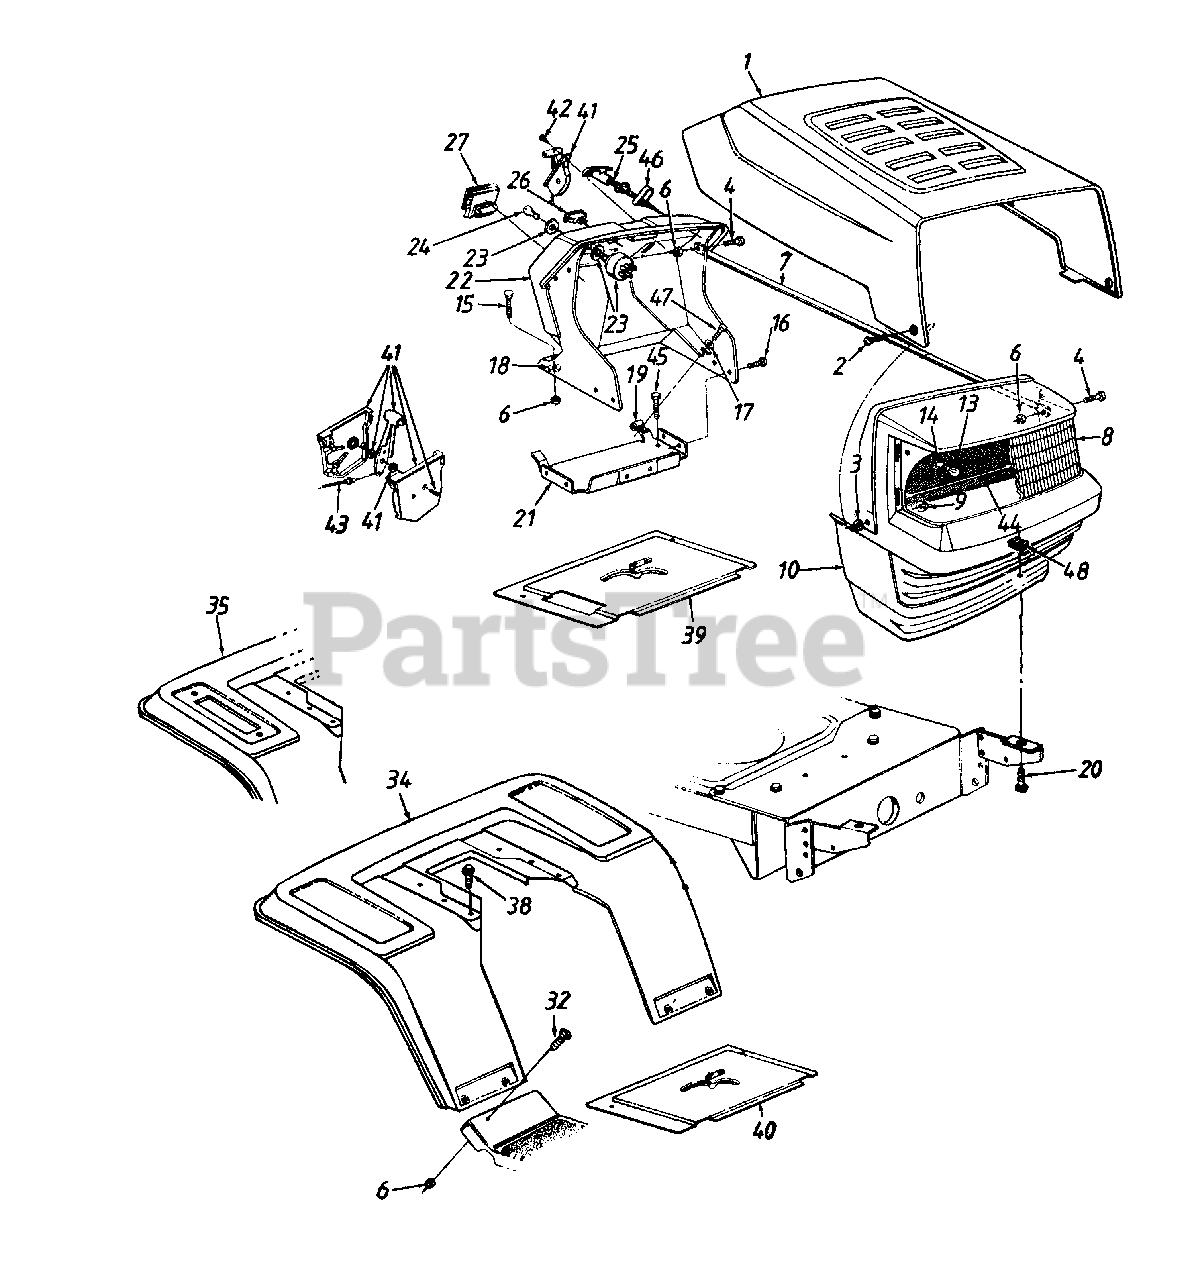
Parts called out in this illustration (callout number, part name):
4	Hex Bolt 1/4-20 x .62" Lg.
6	Hex Sems Nut 1/4-20 Thd.
8	Headlight Lens (w/o Logo)
9	i Flange L-Nut 1/4-20 Thd.
10	Grille
13	Lamp
14	Socket
15	Carriage Bolt 1/4-20 x .75" Lg.
16	Hex Wash. Hd. TT-Tap Scr./4-20 x .5" Lg.
17	Fl-Wash. .281" I.D. x .73" O.D.
18	Bolt Retainer 1/4" I.D.
19	Speed Nut 1/4-20 Thd.
20	Hex Bolt 5/16-18 x .75" Lg.
23	Ignition Switch
24	Ignition Key
25	Choke Control 23" Lg.
26	Light Switch
27	Ammeter
32	Truss Mach. Scr. 1/4-20 x .5" Lg.
41	Throttle Box Ass'y.
42	Truss Mach. AB-Tap Scr.#10 x .5" Lg.
43	Throttle Control Wire 18.5" Lg.
44	Grille Reflector Label
45	Hex Wash. Hd. B-Tap Scr. 5/16-18 x .5" Lg.
46	Choke Retainer
47	Hex TT-Tap Scr. 1/4-20 x .75" Lg.
48	U-Nut 5/16-18 Thd.
